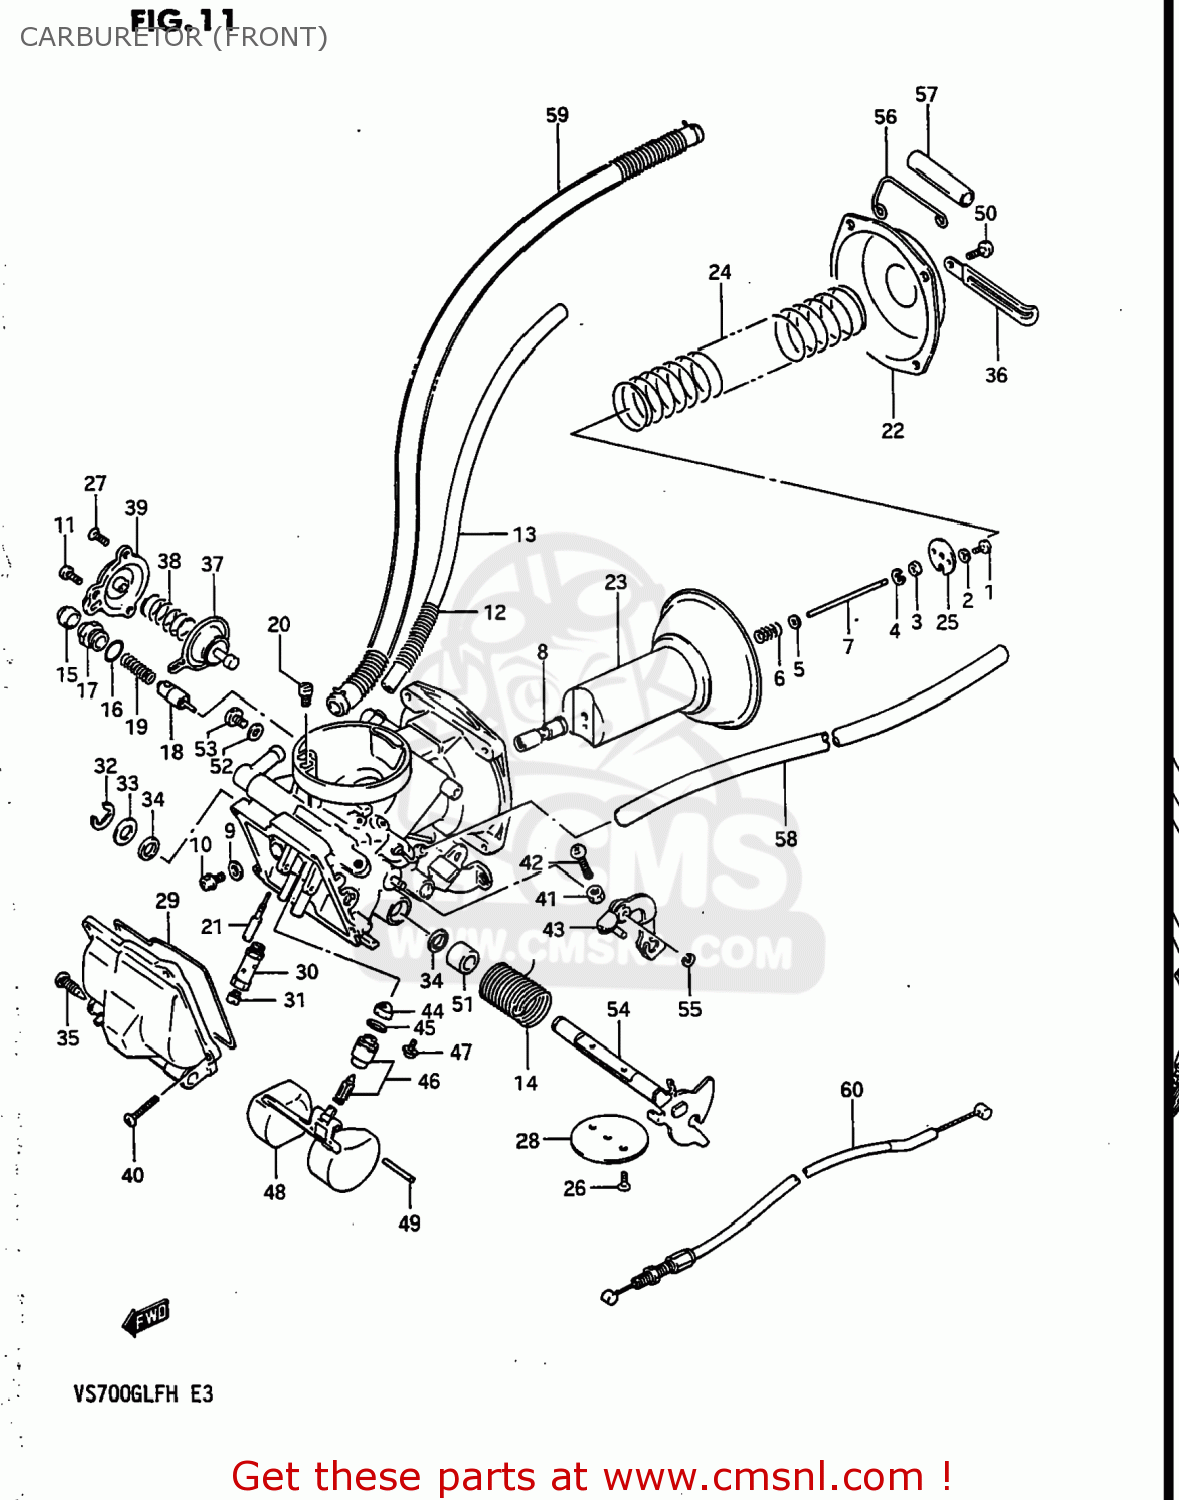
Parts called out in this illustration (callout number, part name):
1	SCREW
2	LOCK WASHER
3	RING
4	CAP,LEVER
5	WASHER
6	SPRING
7	NEEDLE JET
8	JET,NEEDLE
9	WASHER,NEEDLE NOZZLE
10	SCREW
11	SCREWM4X0.7X10
12	SPRING
13	HOSE
14	SPRING
15	CAP
16	O RING
17	HOLDER,GUIDE
18	PLUNGER
19	SPRING
20	JET
21	JET,PILOT(32.5)
22	COVER,DIAPHRAGM
23	DIAPHRAGM,CARBURETOR
24	SPRING,DIAPHRAGM
25	PLATE
26	SCREW
27	SCREW
28	VALVE,THROTTLE
29	GASKET,FLOAT CHAMBER
30	HOLDER,MAIN JET
31	JET,MAIN (132.5)
32	E RING
33	GASKET,THROTTLE SHAFT (NAS)
34	SEAL,THROTTLE SHAFT
35	SCREW,DRAIN
36	CLAMP L:35
37	DIAPHRAGM ASSY
38	SPRING
39	COVER
40	SCREW
41	NUT
42	SCREW
43	LEVER,ASSY
44	FILTER
45	O-RING,NEEDLE VALVE
46	VALVE ASSY,NEEDLE
47	SCREW
48	FLOAT
49	PIN,FLOAT
50	SCREW 5X12
51	RING,THROTTLE VALVE
52	WASHER
53	SCREW
54	SHAFT ASSEMBLY,THROTTLE
55	E-RING
56	CLIP
57	HOSE
58	HOSE
59	HOSE
60	CABLE,IDLE SYNCRO
